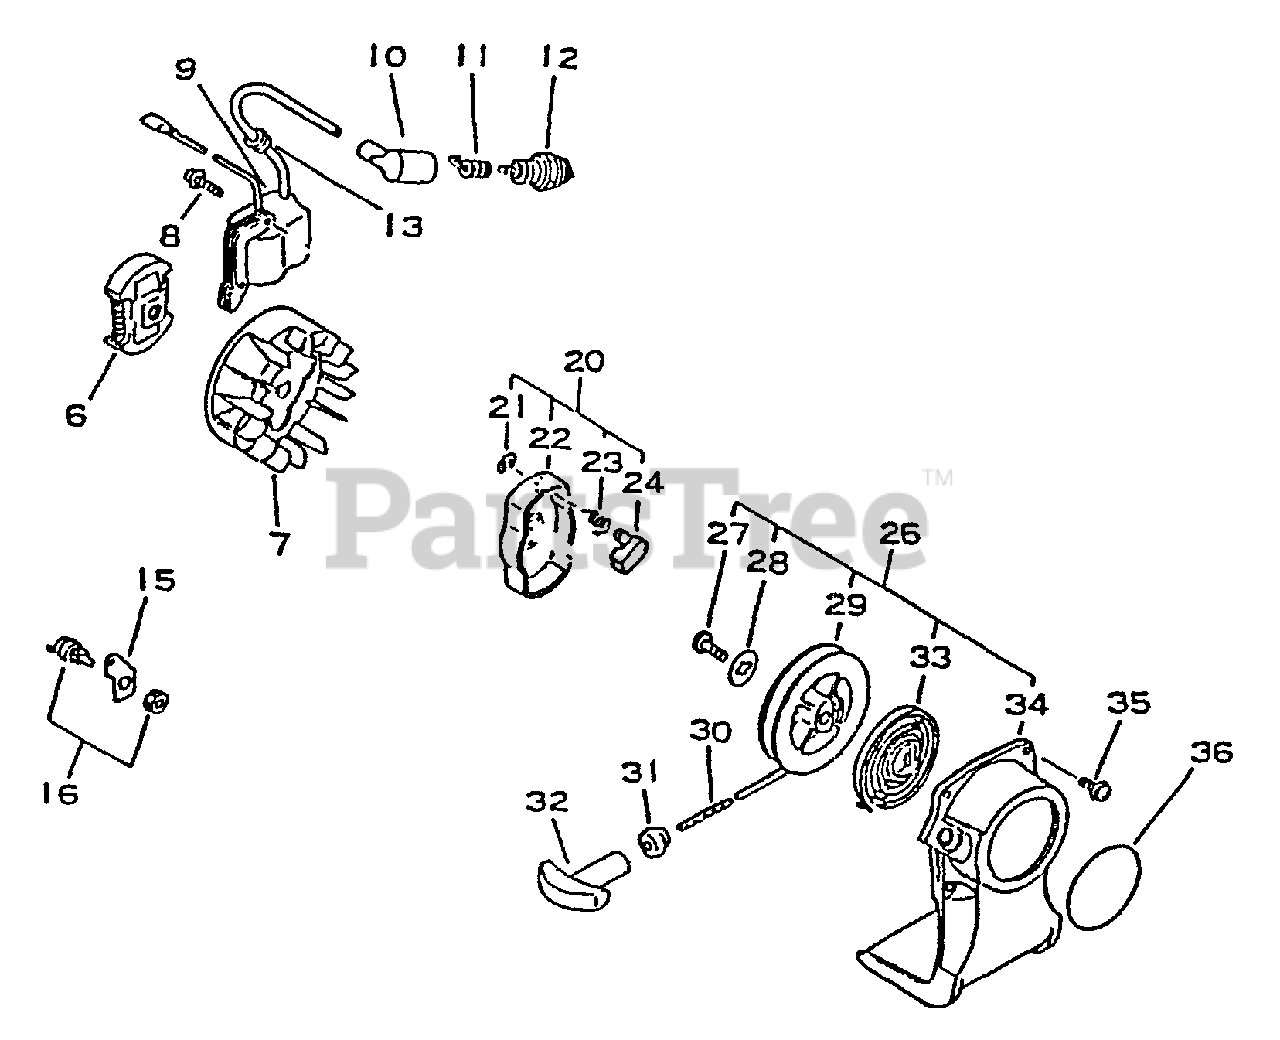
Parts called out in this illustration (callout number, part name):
6	CLUTCH ASSY
7	FLYWHEEL
8	SCREW 4×22
9	COIL, IGNITION
10	CAP, SPARK PLUG
11	TERMINAL, SPARK PLUG
12	SPARK PLUG - BPM7A
12	SPARK PLUG - CJ-7Y
15	BRACKET, SWITCH
16	SWITCH, ON-OFF
20	STARTER PAWL ASSY
21	E-RING 4
22	CATCHER, PAWL
23	SPRING, RETURN
24	PAWL, STARTER
26	STARTER ASSY - BLACK
28	WASHER
29	REEL, ROPE
30	ROPE, STARTER
31	GUIDE, ROPE
32	GRIP, STARTER
33	SPRING, RECOIL
34	CASE, STARTER - BLUE
35	SCREW 4×16
36	LABEL - ECHO
C12	SPARK PLUG - BPMR7A
C12	SPARK PLUG - RCJ7Y
